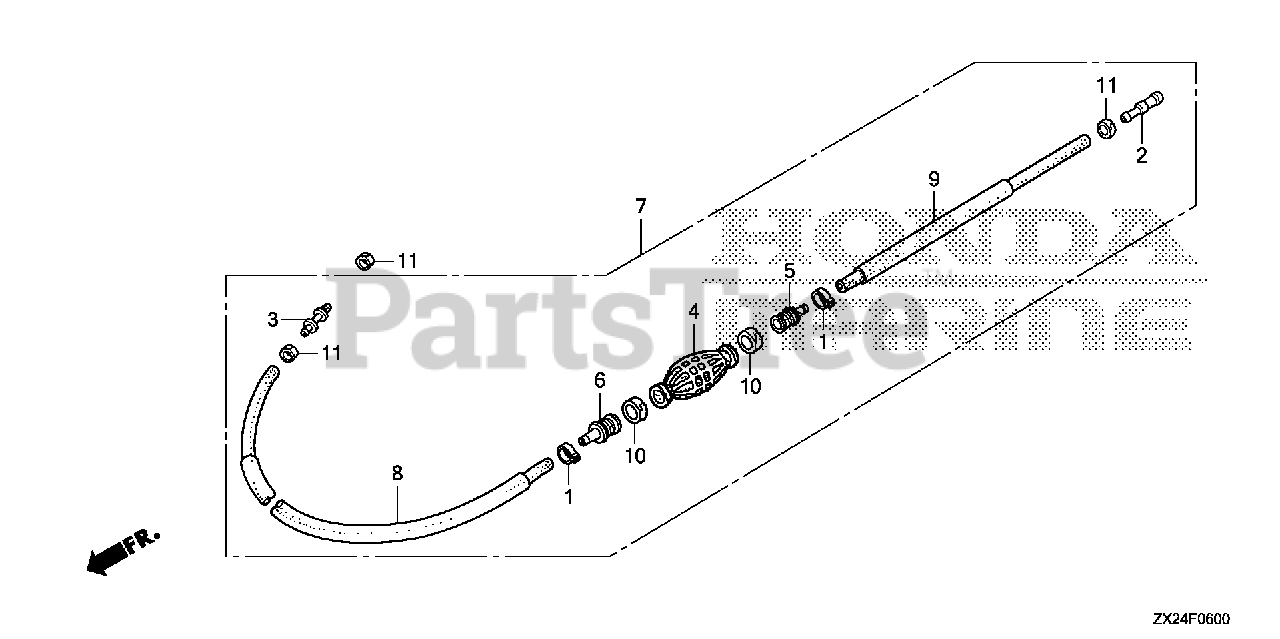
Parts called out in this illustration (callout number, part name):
1	CLAMP, FUEL TUBE (14.0)
2	JOINT, FUEL TUBE
3	JOINT, FUEL TUBE
4	BULB, PRIMER
5	VALVE, IN.
6	VALVE, OUTLET
7	TUBE ASSY., FUEL TANK
8	TUBE, FUEL LONG (7.3X2000)
9	TUBE, FUEL SHORT
10	BAND, TUBE CLIP (20MM)
11	BAND, TUBE CLIP (12.5MM)
